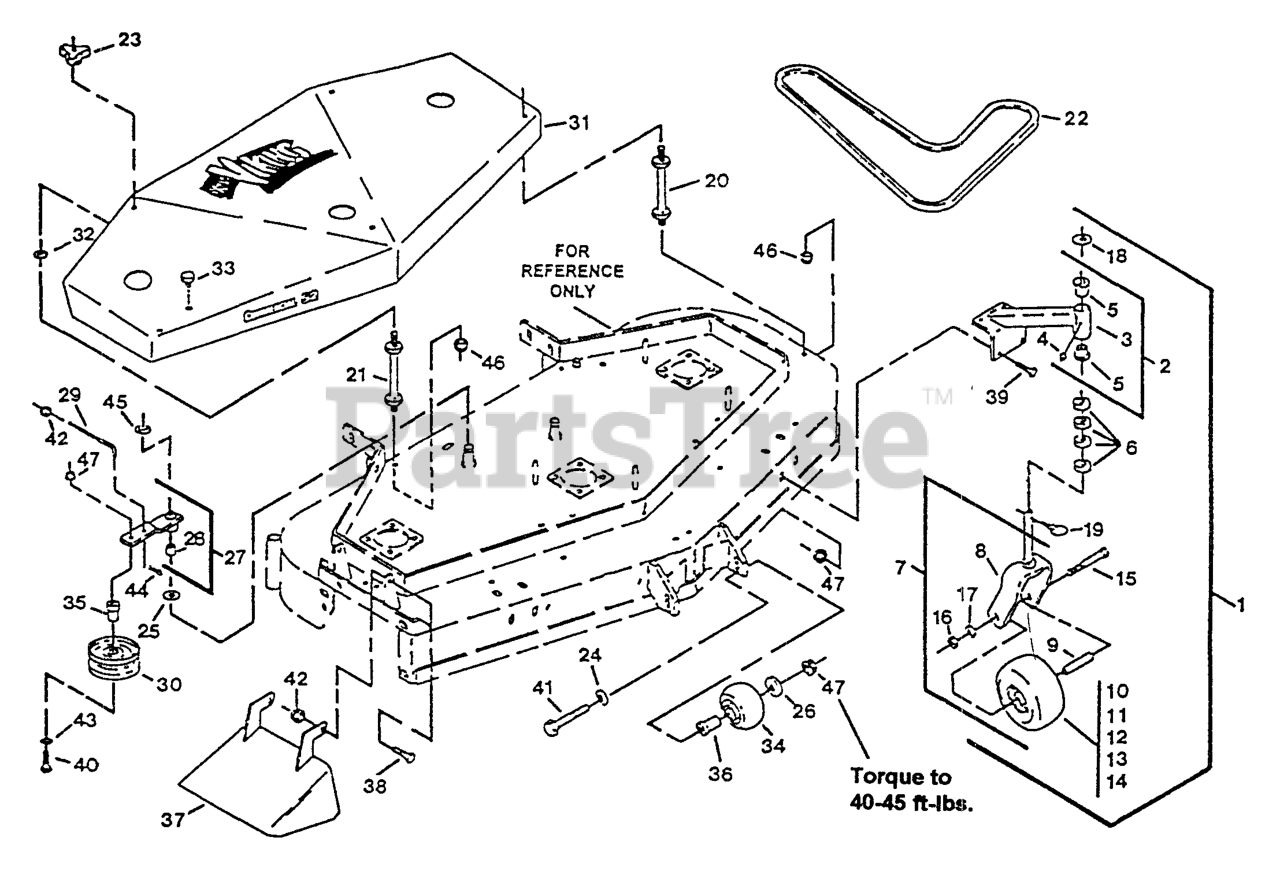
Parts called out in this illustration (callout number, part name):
1	CASTER/MOUNT ASM
2	SUPPORT ASM
5	BEARING-FLANGED
6	SPACER-CASTER
13	BEARING
14	BUSHING
18	WASHER-FLAT
20	STUD-SHIELD, BELT (SHORT)
21	STUD-SHIELD, BELT (LONG)
23	KNOB-3 PRONG
25	WASHER-SPINDLE
27	ARM WLDMNT W/BUSHING
28	BEARING,POWDERED METAL
29	LINKAGE
30	IDLER,PULLEY
34	ROLLER-SCALP, ANTI
35	BUSHING-IDLER
36	BUSHING-ROLLER
37	WLD,CHUTE DISCHARGE
44	PIN-COTTER
